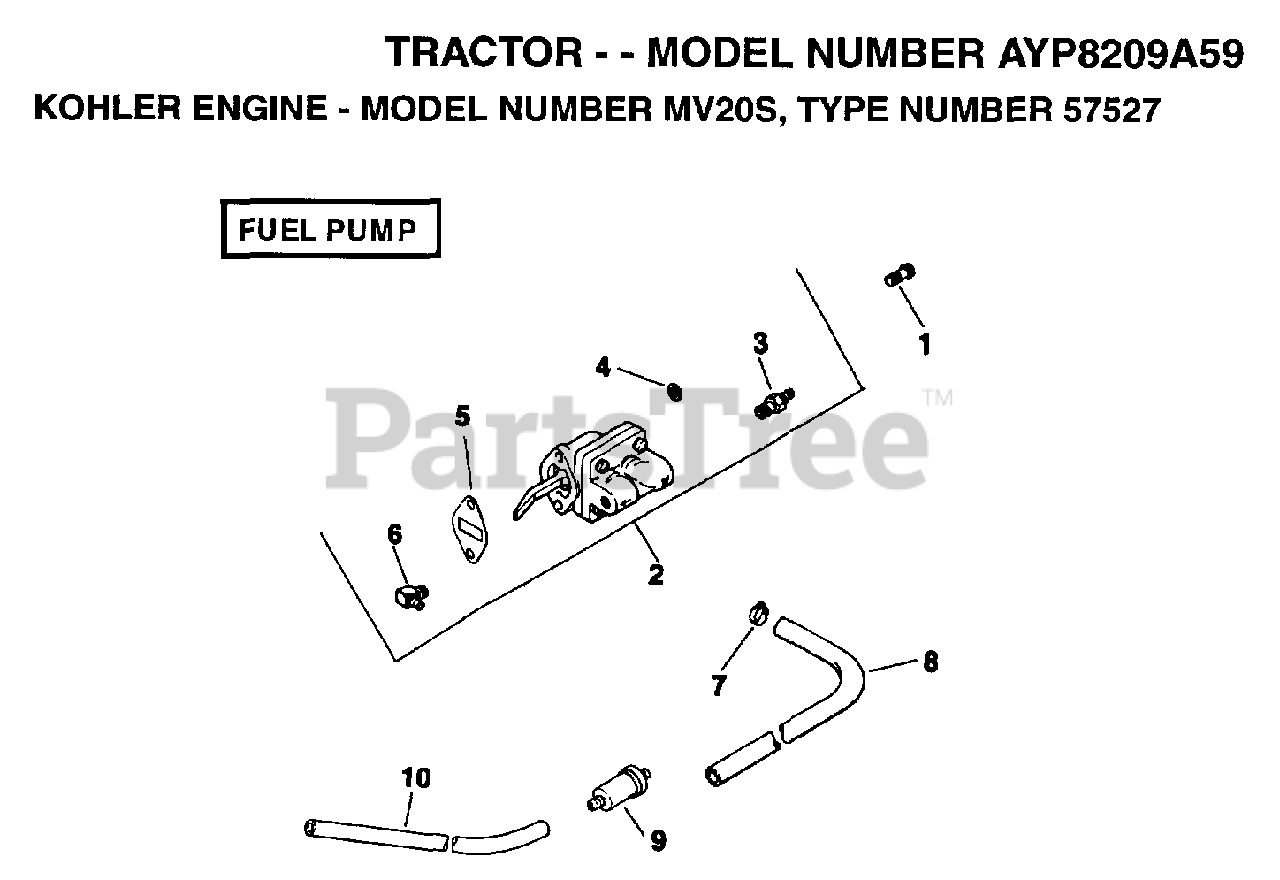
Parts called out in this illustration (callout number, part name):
3	CONNECTOR, HOSE
4	WASHER, PLAIN 1/4
8	LINE FUEL 11-1/2"
10	LINE, FUEL 8"
